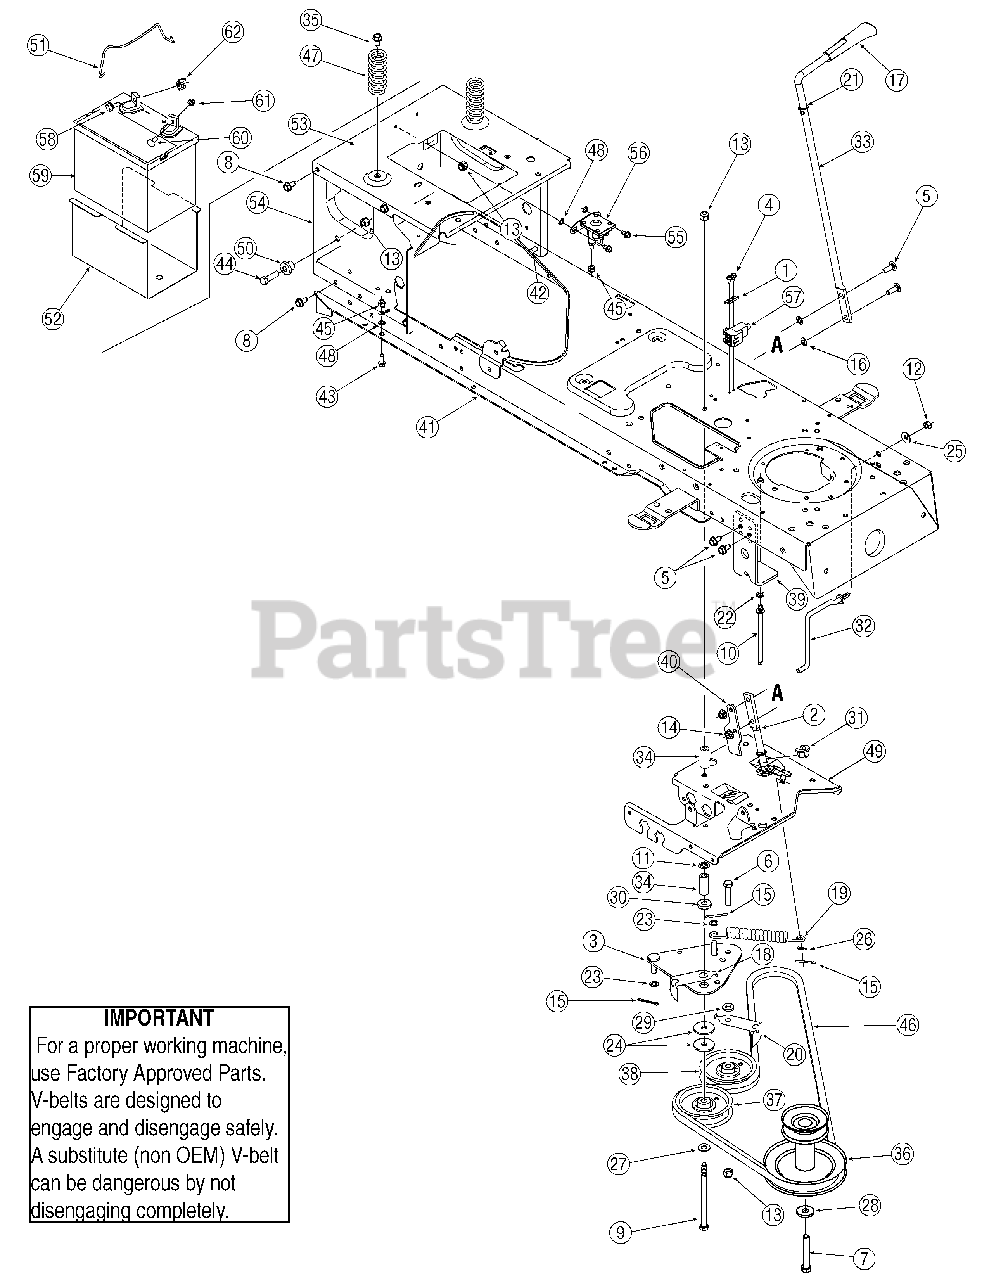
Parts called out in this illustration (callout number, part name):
1	Plate, Switch
2	Lever Assembly, Engagement
4	Screw, #10-16, 0.500
5	Screw, Carriage, 5/16-18, 1.00
6	Screw, 3/8-16, 1.75, Gr5
7	Screw, 7/16-20, 2.75, Gr5
8	Screw, 5/16-12, 0.750
9	Screw, 3/8-16, 5.50, Gr5
10	Pin, Belt Guard, 5/16 x 4.75
11	Nut, Push, 3/8
12	Nut, Flange Lock, 5/16-18, GrF
13	Nut, Flange Lock, 3/8-16, GrF
14	Nut, Flange Lock, 5/16-18, Gr5
15	Pin, Cotter, 1/8 x 1.25
16	Nut, Speed, .3125 ID
17	Knob, PTO
19	Spring, Extension, .75 OD x 6.75
20	Belt Guard
21	Washer, Flat, .510 x .750
22	Washer, Lock, 5/16
23	Washer, Flat, .385 x .62 x .063
24	Washer, Flat, .390 x 1.500 x .134
25	Washer, Bell, .340 x .872 x .060
26	Washer, Flat, .344 x .688 x.065
27	Washer, Flat, .406 x .875 x .059
28	Washer, Flat, .450 x1.250 x .164
29	Washer, Flat, .407 x.812 x .135
30	Spacer, Shldr, 1.00 x .38 x .38
31	Bearing, Flange, Hex Split .500 ID
32	Keeper Rod, Belt
33	Engagement Handle, Deck
34	Spacer, .385 ID x .635 x 1.54
35	Screw, 5/16-18 x .750
36	Pulley, Engine, 3.39 x 6.12 Dia
37	Pulley, Idler, V-type 5/8 x 4.0 Dia
38	Pulley, Idler, 3.50 Diameter
43	Screw, 1/4-20, 0.750
44	Screw, 3/8-16, 1.25, Gr5
45	Nut, Flange Lock, 1/4-20, GrF
47	Spring, Compr., 1.28 OD x 3.125
48	Washer, Lock, 1/4, External
50	Spacer, Shoulder, .38 x 1.0
51	Hold Rod, Battery
56	Solenoid, 12V, 100 Amp
57	Switch, Interlock
58	Screw, Shoulder, .250 x .150
59	Battery, 235 CCA
60	Screw, Carriage, 1/4-20, .75, Gr5
61	Nut, Sems, 1/4-20
62	Nut, Wing, 1/4-20
